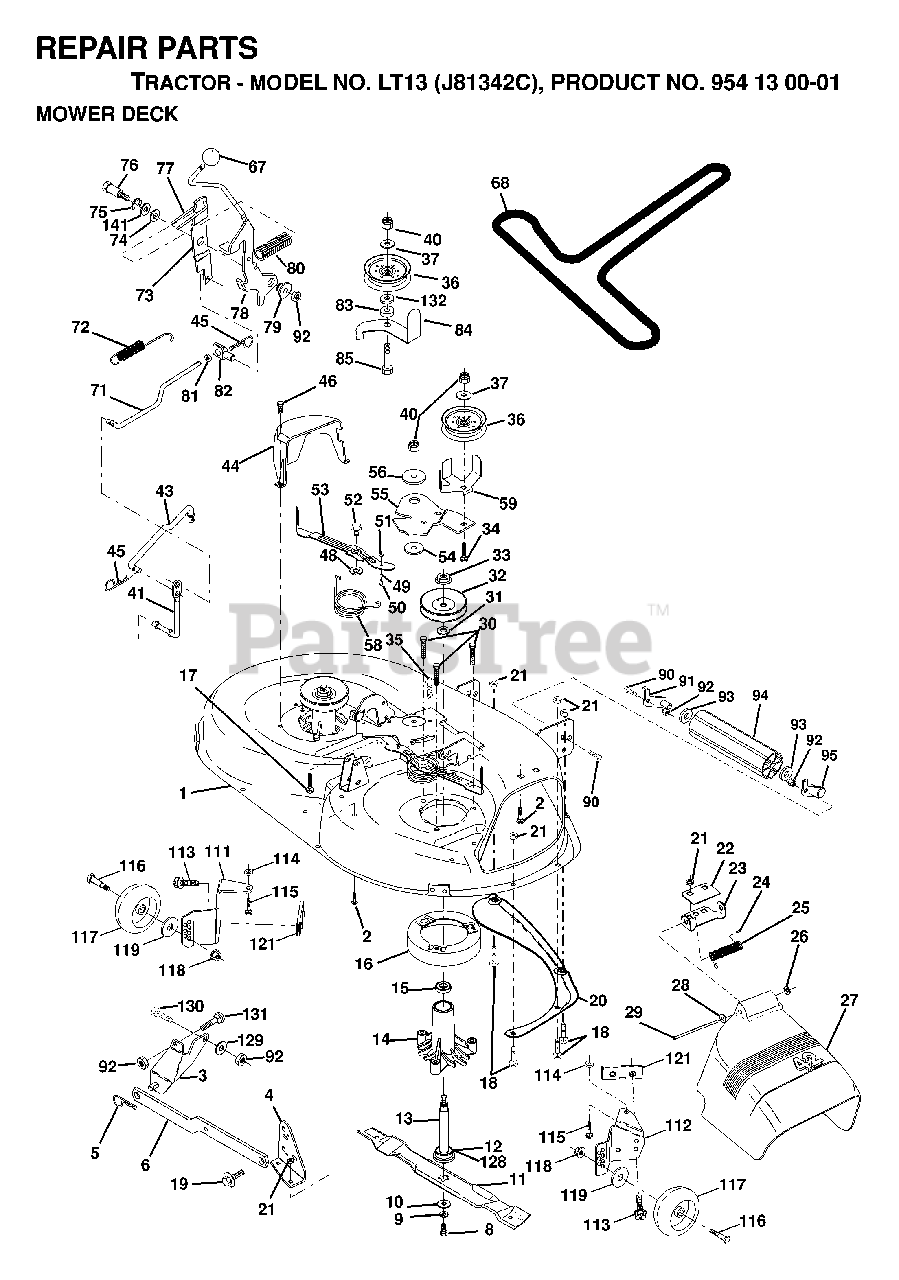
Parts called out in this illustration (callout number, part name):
1	DECK 42"
2	BOLT
3	BRKT ASM SWAY BAR
4	BRKT DECK SW BAR
5	RETAINER-SPRNG RB
6	REAR SUSP ARM
8	BLADE BOLT
9	LOCKWASHER
10	WASHER.BLADE
12	BEARING
13	SHAFT ASM VENT
14	HSG MANDREL
16	STRIPPER
17	BOLT
18	BOLT
19	BOLT SHD 5/16-18
20	BAFFLE
21	LOCKNUT
22	STIFFENER BRACKET
23	DEFLECTOR BRACKET
24	CAP-SLEEVE LT
25	SPRING TORSION
26	NUT PUSH M
27	SHIELD.DEFLECTOR.MOWER.42".BLK
28	WASHER
29	ROD.HINGE
30	SCREW
31	WASHER
32	PULLEY/MANDREL
33	NUT
34	BOLT
35	FASTENER.XMAS.TREE
36	FLAT IDLER PULLEY
40	LOCKNUT
41	PIVOT ROD
43	CLUTCH ROD
44	GUARD MANDREL LH BLACK
45	RETAINER M
46	SCREW.1/4-20X5/8
49	ROLLER ASSY
50	BOLT
53	ARM ASM PAD BRAD
54	HARDENED WASHER
55	ARM IDLER 42" MOWER LT/YT
56	SPACER RETAINER
59	GUARD, BELT
67	KNOB T (3/8 HOLE)
71	CLUTCH ROD
72	RETURN SPRING
73	ARM CLUTCH SECONDARY
75	RING CLIP
77	KEEPER SPRING
78	ARM ASM CLUTCH PRIMARY
79	BUSHING.FLANGE.E-RING.GROOVE
80	SPRING-CLUTCH
81	NUT
90	BOLT
91	BRACKET LH (A)
92	NUT
94	NOSE ROLLER
95	BRACKET RH (B)
111	BRACKET WHEEL GAUGE LH 42" DK
112	BRACKET WHEEL GAUGE RH 42" DK
113	SCREW
114	NUT
115	BOLT
118	LOCKNUT
119	WASHER
121	BRACKET.EXTRD.GWL
128	WASHER FELT
132	WASHER GT
